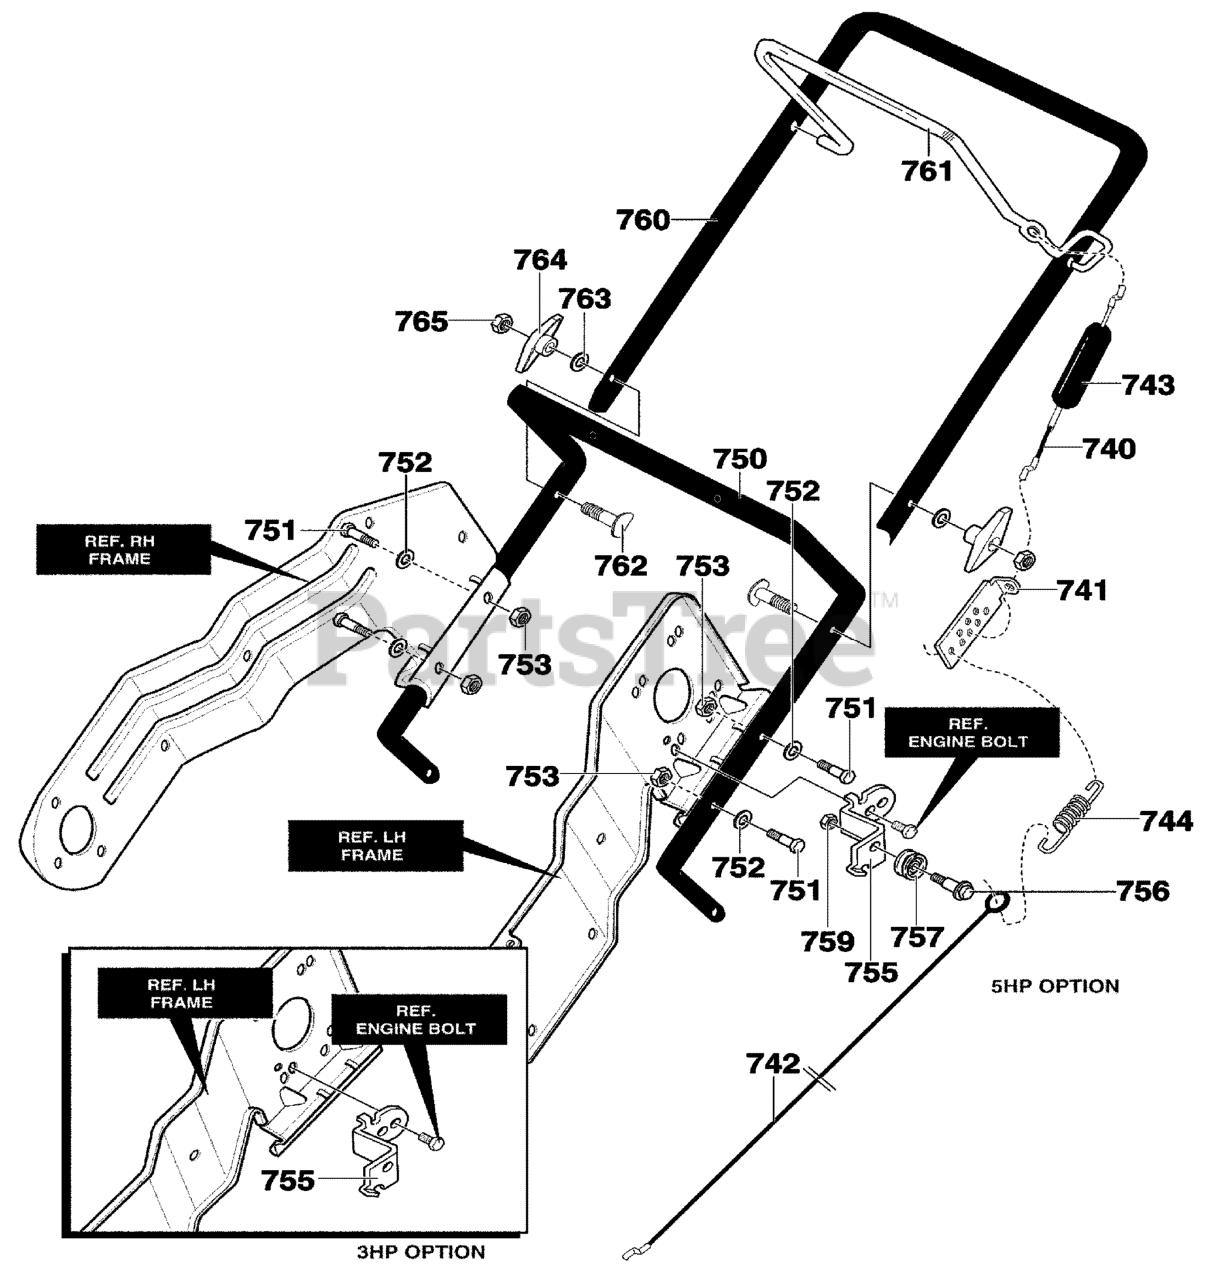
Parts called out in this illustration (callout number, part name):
740	CABLE, UPPER
741	BRACKET, CABLE ADJ
742	CABLE, LOWER CONTROL
743	BOOT, CLUTCH SPRING
744	SPRING, EXTENSION
750	HANDLE, LOWER
751	SCREW, 1/4-20X1.25
752	WASHER, FLAT
753	NUT, 1/4-20 YZ
755	BRACKET, CABLE
757	PULLEY
759	NUT, 1/4-20
760	UPPER HANDLE
761	BAIL, CONTROL
762	BOLT
763	WASHER, FORM
764	KNOB, T 3.00 WD
765	NUT, 5/16-18
